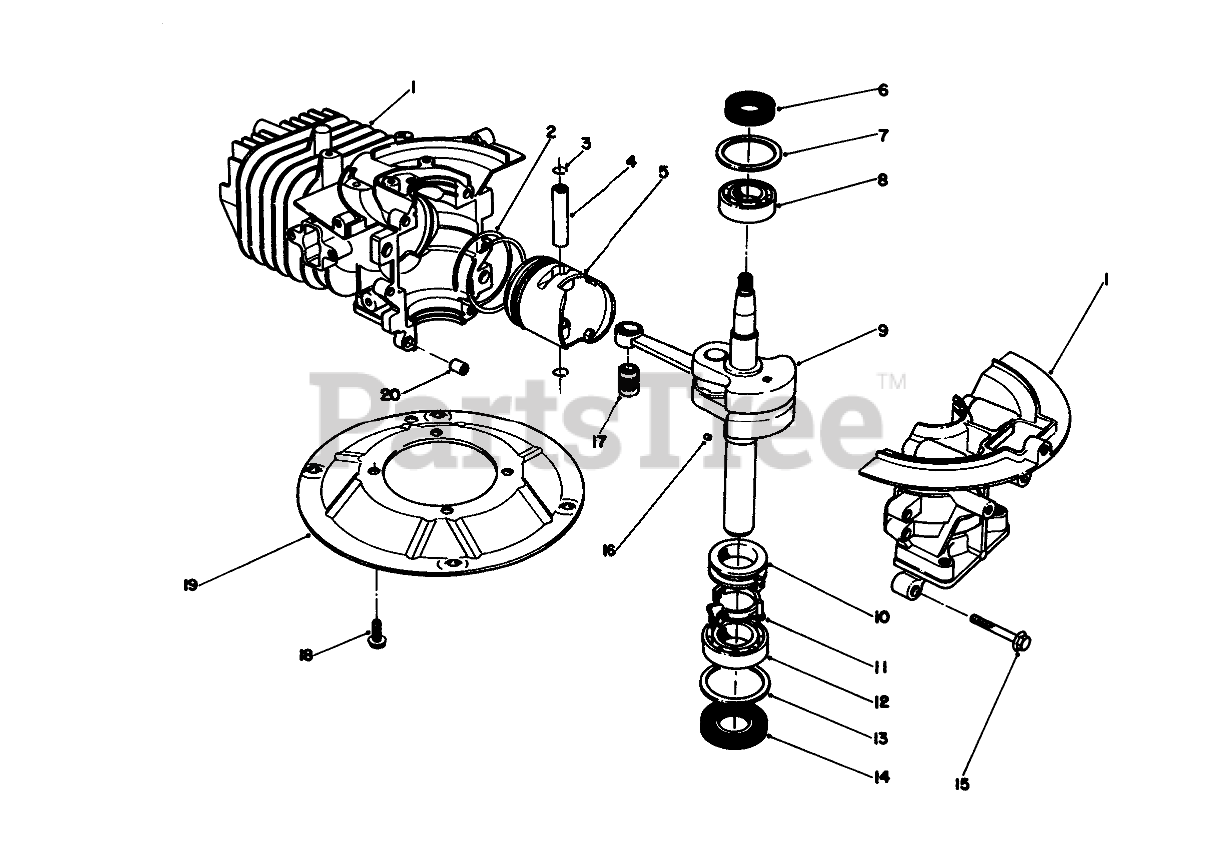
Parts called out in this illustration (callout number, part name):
1	CRANKCASE
2	RING SET
4	PIN-PISTON
5	Piston
6	OIL SEAL
7	WASHER-UPPER
8	BEARING-UPPER
9	CRANKSHAFT
10	SPACER
11	BRACKET
12	LOWER BRG
13	WASHER-LOWER
14	SEAL-OIL
17	BEARING
19	PLATE-MOUNTING
